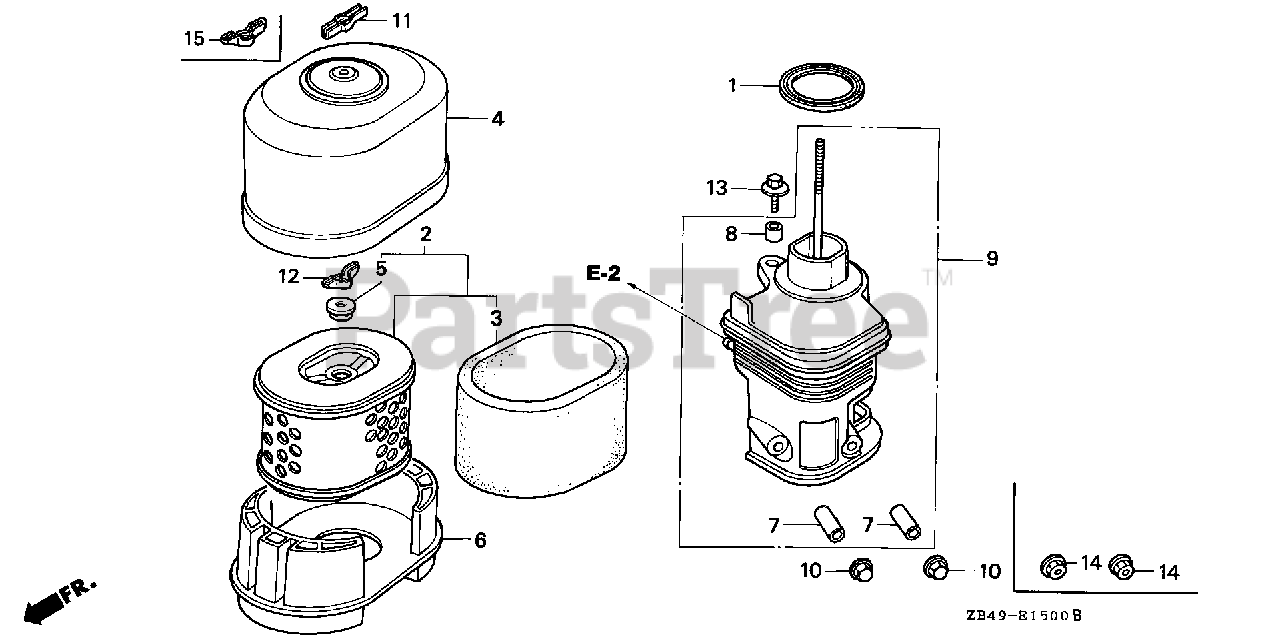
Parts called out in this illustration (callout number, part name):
1	GASKET, ELBOW
2	ELEMENT, AIR CLEANER (DUAL)
3	FILTER (OUTER)
4	COVER, AIR CLEANER (DUAL)
5	GROMMET, AIR CLEANER
6	NOSE, MUFFLER
7	COLLAR, AIR CLEANER
8	COLLAR B, AIR CLEANER
9	ELBOW, AIR CLEANER
9	ELBOW COMP, AIR/C
12	NUT, TOOL BOX SETTING
13	BOLT-WASHER (6X22)
14	NUT, FLANGE (6MM)
15	NUT, TOOL BOX SETTING
